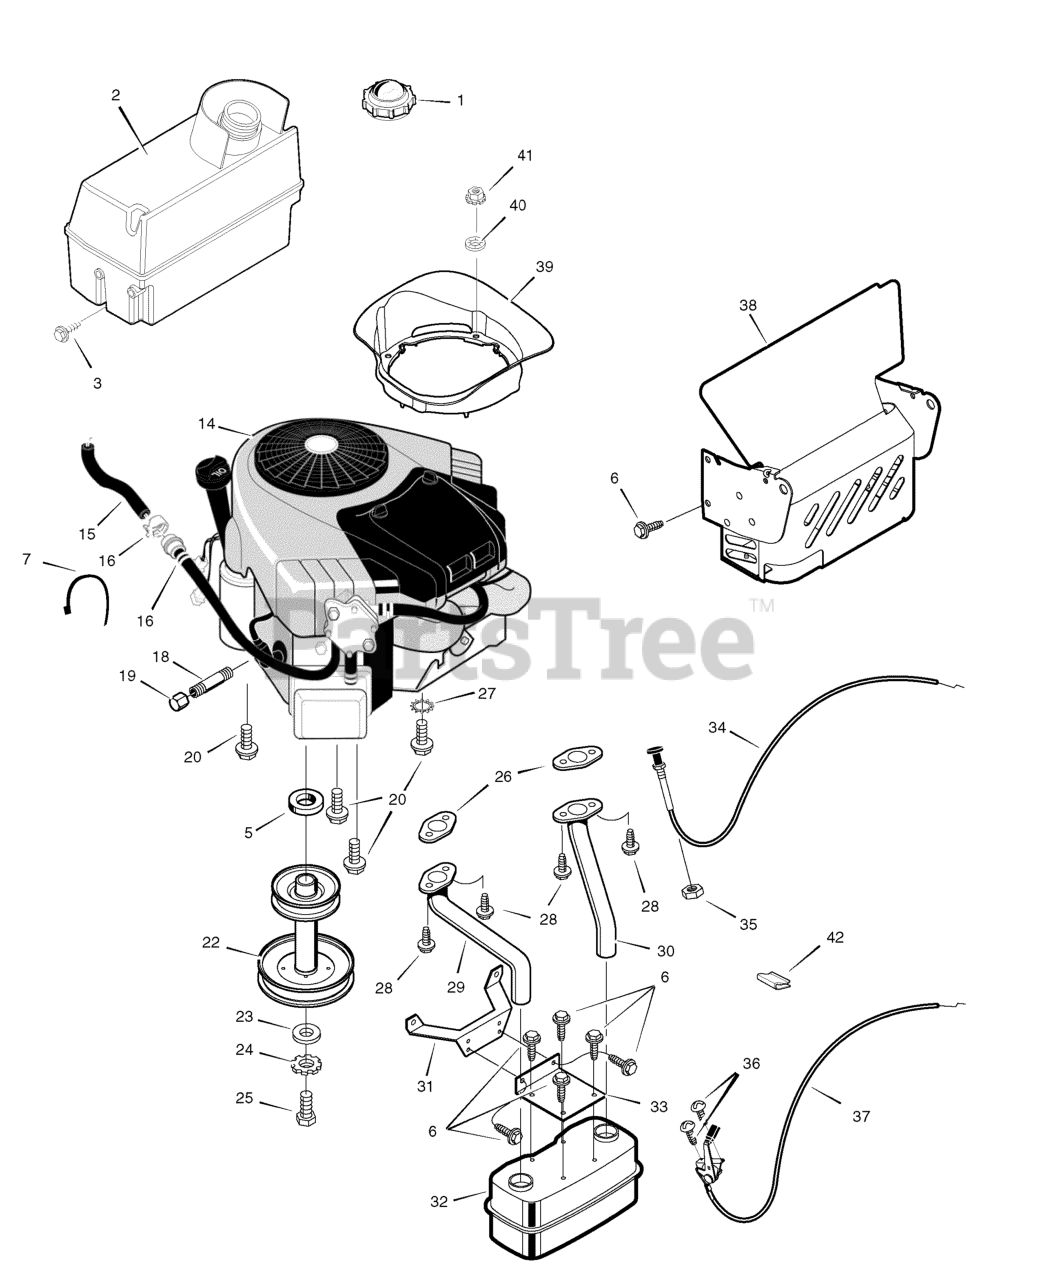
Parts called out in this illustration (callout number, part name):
1	Cap, Fuel
2	Tank, Fuel
5	Spacer, Engine
7	Tie Strap
14	Engine *
15	Fuel Line (Must cut to length)
16	Clamp
18	Pipe, Oil Drain
19	Cap, Oil Drain
20	Bolt
22	Pulley, Stack
24	Lockwasher
27	Washer, Star
29	Tube, Right Exhaust
30	Tube, Left Exhaust
31	Bracket, Muffler Mount
32	Muffler
33	Bracket, Muffler
35	Nut
37	Control, Throttle
38	Shield Assembly, Heat
40	Speed Nut
41	Plenum Nut
42	Clip Wire
